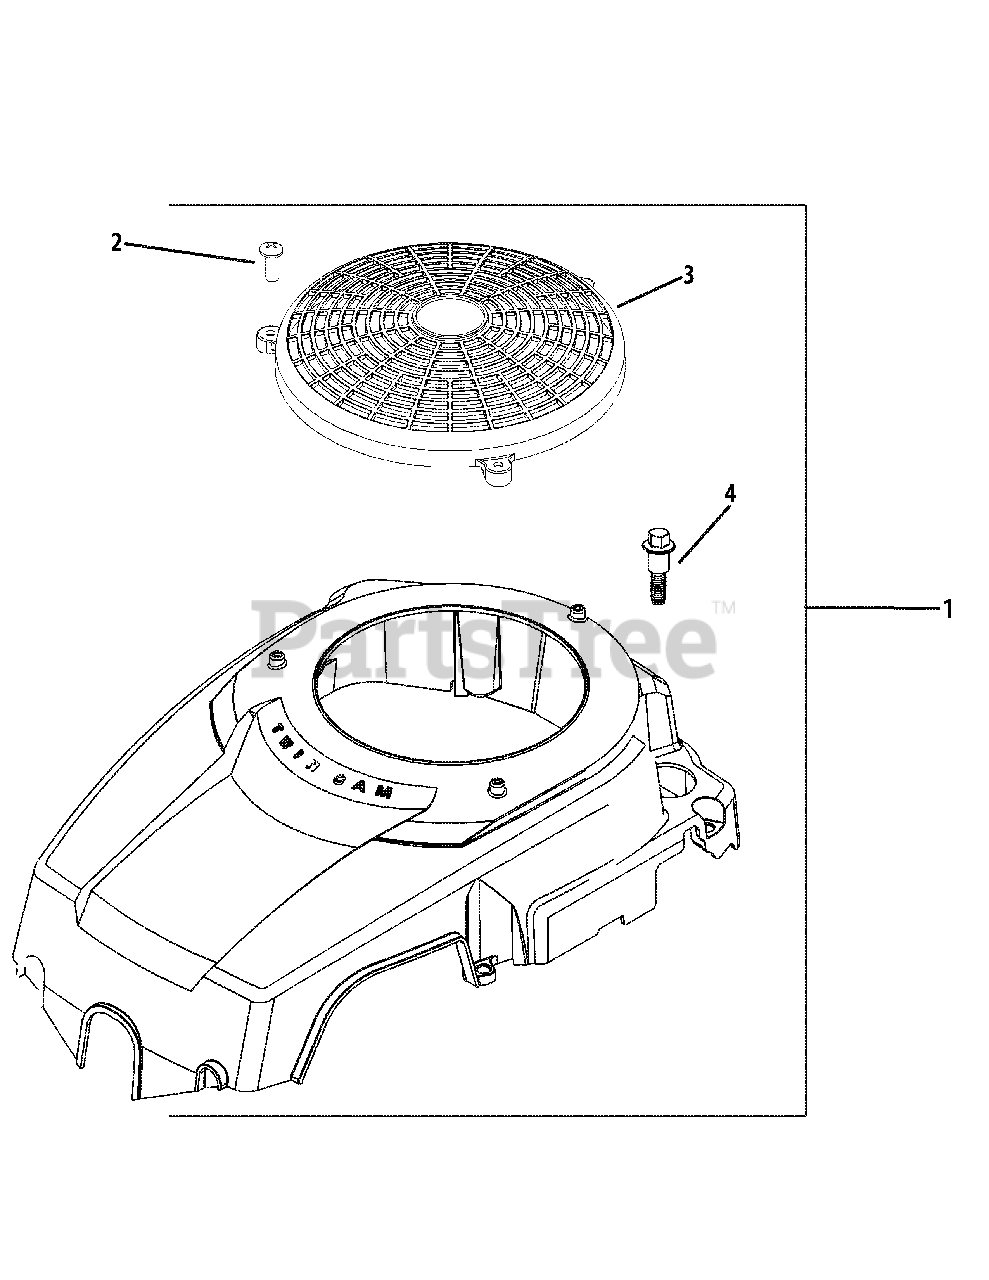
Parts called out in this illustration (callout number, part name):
1	Blower Housing & Guard
2	Phillips Head Screw, #11-16 X 1/2"
4	Shd Thd Frm Screw, M6 X 1 X 26
